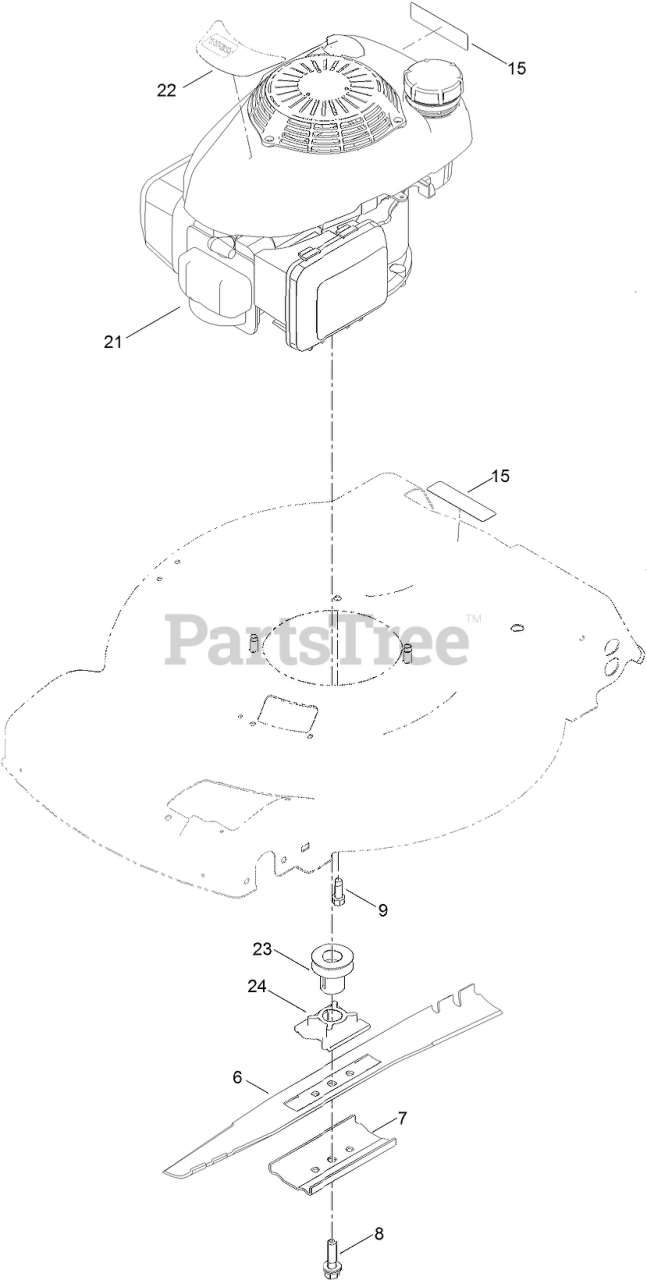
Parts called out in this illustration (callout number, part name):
6	BLADE-22 INCH
7	SUPPORT-BLADE
8	BOLT-BLADE
9	SCREW-TAPTITE
15	DECAL-ARRESTOR, SPARK
22	DECAL-SHROUD, HONDA
23	PULLEY
24	RETAINER-BLADE
